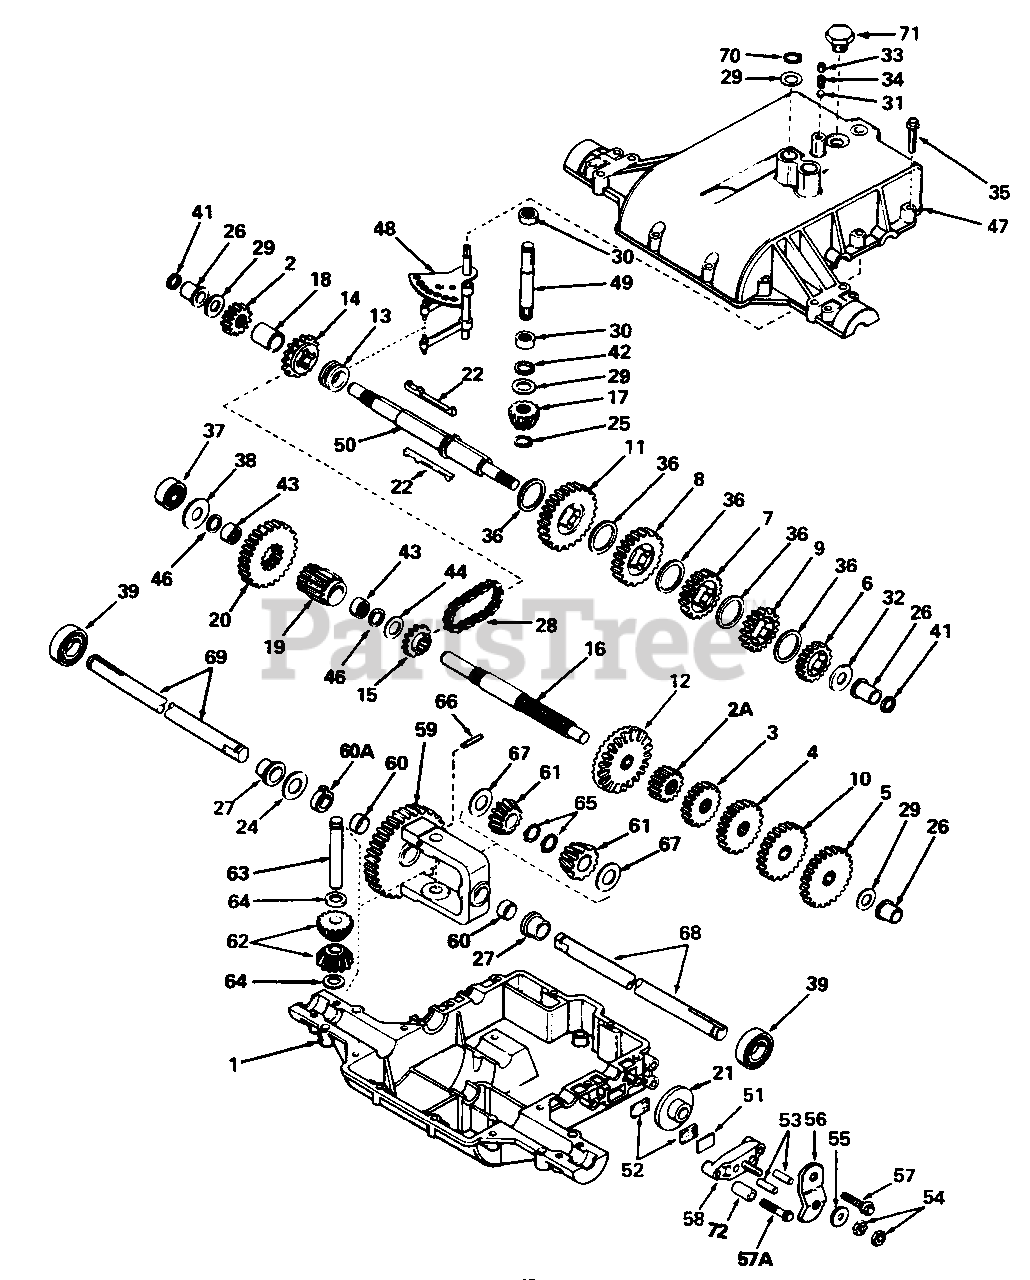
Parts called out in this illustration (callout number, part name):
1	CASE, Transaxle
2	GEAR, Spur (15 teeth)
2A	GEAR, Spur (12 teeth)
3	GEAR, Spur (20 teeth)
4	GEAR, Spur (25 teeth)
5	GEAR, Spur (30 teeth)
6	GEAR, Spur (20 teeth)
7	GEAR, Spur (25 teeth)
8	GEAR, Spur (30 teeth)
9	GEAR, Spur (22 teeth)
10	GEAR, Spur (28 teeth)
11	GEAR, Spur (37 teeth)
12	GEAR, Bevel (42 teeth)
13	COLLAR, Shift
14	SPROCKET (14 teeth)
15	SPROCKET (10 teeth)
16	SHAFT, Counter
17	BEVEL PINION, Input
19	PINION, Output
20	GEAR, Output
21	DISK, Brake
25	RING, Retaining
26	BUSHING, Flanged
27	BUSHING, Flanged
28	CHAIN, Roller (No. 41 chain, 22 links)
29	WASHER, Thrust
30	BEARING, Thrust
31	BALL, Steel
32	WASHER, Thrust
33	SCREW, Set, 3/8-16 x 3/8
35	SCREW, Hex Hd., Thd. Form., 1/4-20 x 1-1/4
36	WASHER, Thrust
37	BEARING, Ball
38	WASHER, Flat
39	BEARING, Ball
41	RING, Square Cut
42	RING, Square Cut
43	BEARING, Needle
44	WASHER, Flat
46	RING, Square Cut
47	COVER, Transaxle
48	ROD & FORK ASSY., Shift
49	SHAFT, Input
50	SHAFT, Brake
51	PLATE, Brake Pad
52	PAD, Brake
53	PIN, Dowel
54	LOCKNUT, 5/16-24
55	WASHER, Flat
56	LEVER, Brake
57	SCREW, Hex Hd. Thd. Form., 1/4-20 x 1-1/4
57A	SCREW, Hex Hd., Thd. Form., 1/4-20 x 2-1/4
58	HOLDER, Brake Pad
59	GEAR ASSY., Differential (Incl. 2 of No. 60)
61	GEAR, Bevel
62	PINION, Bevel
63	PIN, Drive
64	WASHER, Thrust
65	RING, Retaining
66	PIN, Roll
67	WASHER, Thrust
68	AXLE (15-1/2" long)
69	AXLE (12-1/2" long)
70	RING, Retaining
71	PLUG, Hex Hd., 9/16-18 thread
